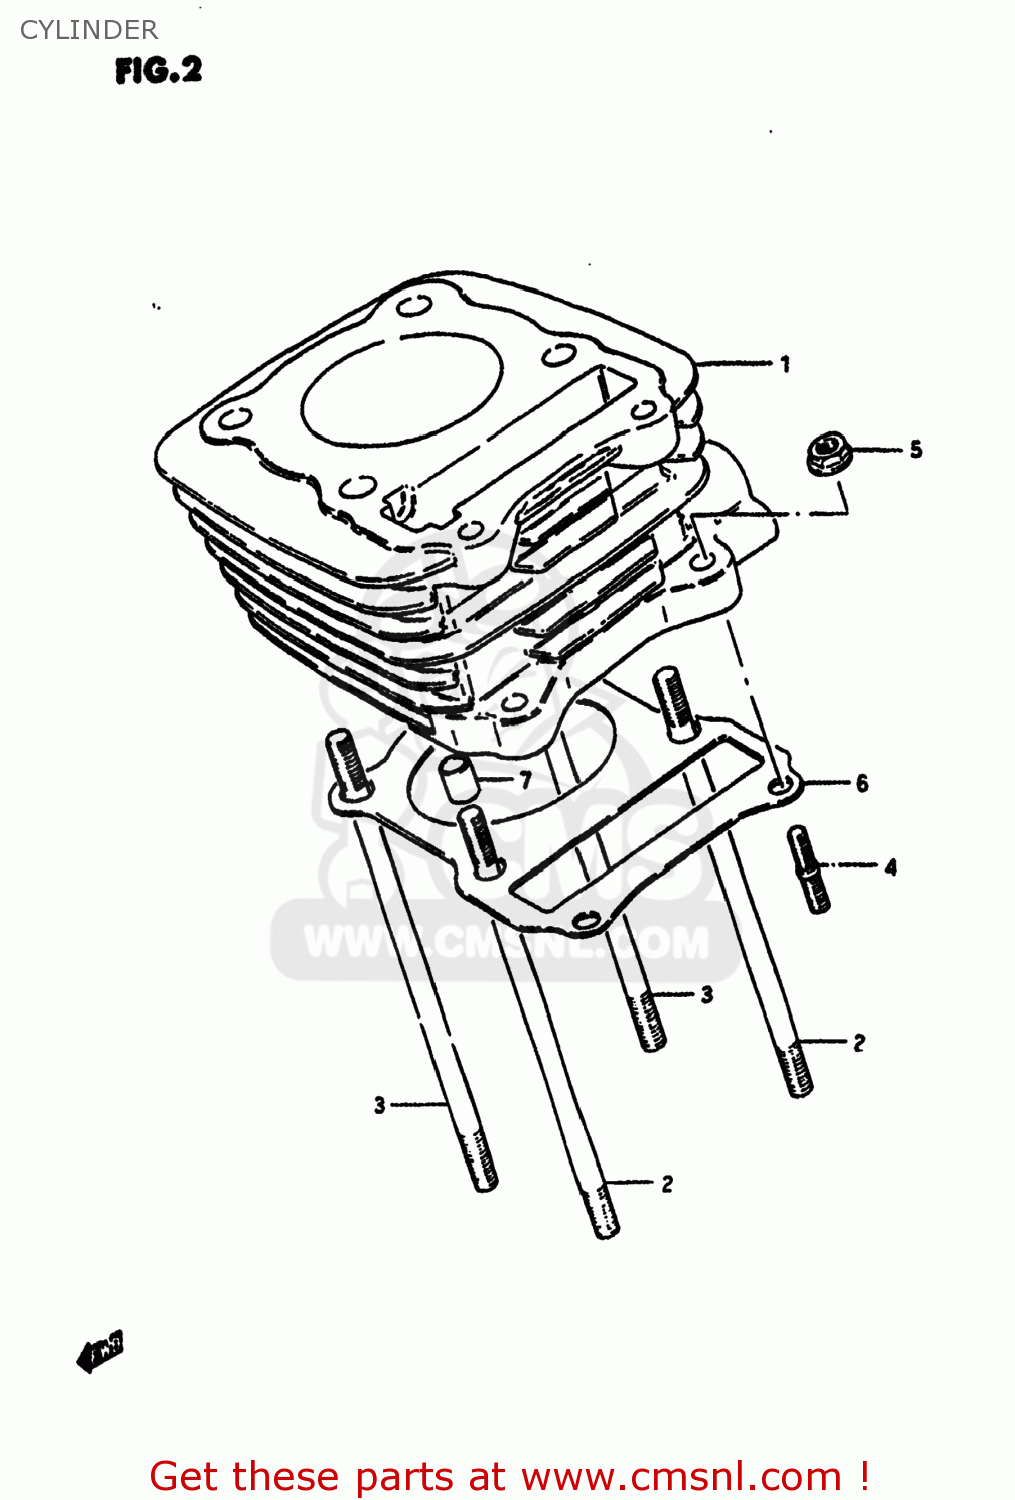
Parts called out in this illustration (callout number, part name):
1	CYLINDER
2	BOLT,STUD
3	BOLT,STUD
4	STUD 6X25
5	NUT
6	GASKET,CYLINDER (MCA)
7	PIN
